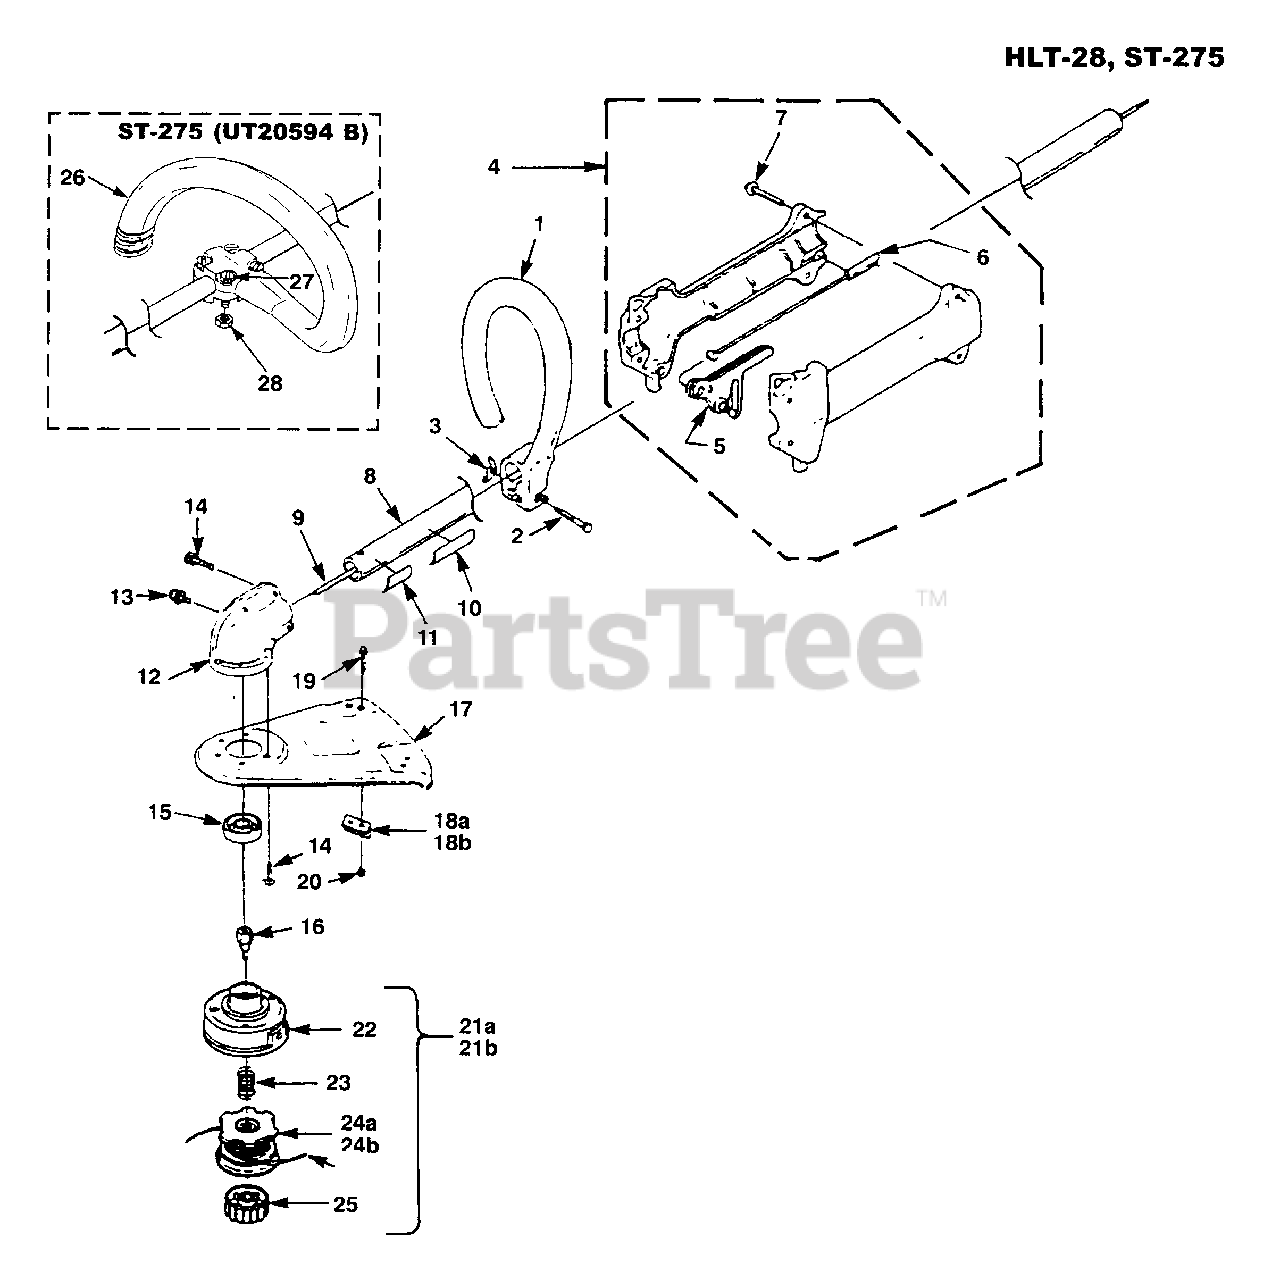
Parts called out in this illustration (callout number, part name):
1	HANDLE KIT - Front Loop
2	SCREW - Hex Hd (1/4-20 X 2")
3	NUT - Wing (1/4-20)
4	HANDLE GRIP ASSEMBLY
5	TRIGGER
6	CABLE - Throttle
7	SCREW - Plastite (8 X 3/4")
8	HOUSING - Drive Shaft
9	SHAFT - Flexible
10	DECAL - Staring Instructions
11	DECAL - Warning
12	GEAR HEAD
13	SCREW - Hex Hd (10-24 X 1/2")
14	SCREW - Hex Hd (10-24 X 5/8")
15	WASHER - Flanged
16	ADAPTOR - Shaft
17	GRASS DEFLECTOR KIT
19	SCREW - Mach Hex Hd (10-24 X 3/8")
20	NUT - Lock Hex (10-24)
22	HOUSING & EYELET
23	SPRING - Compression
25	RETAINER - Spool
26	FRONT HANDLE ("G")
27	SCREW - Hex Hd (10-24 X 1")
28	NUT - Hex (10-24)
